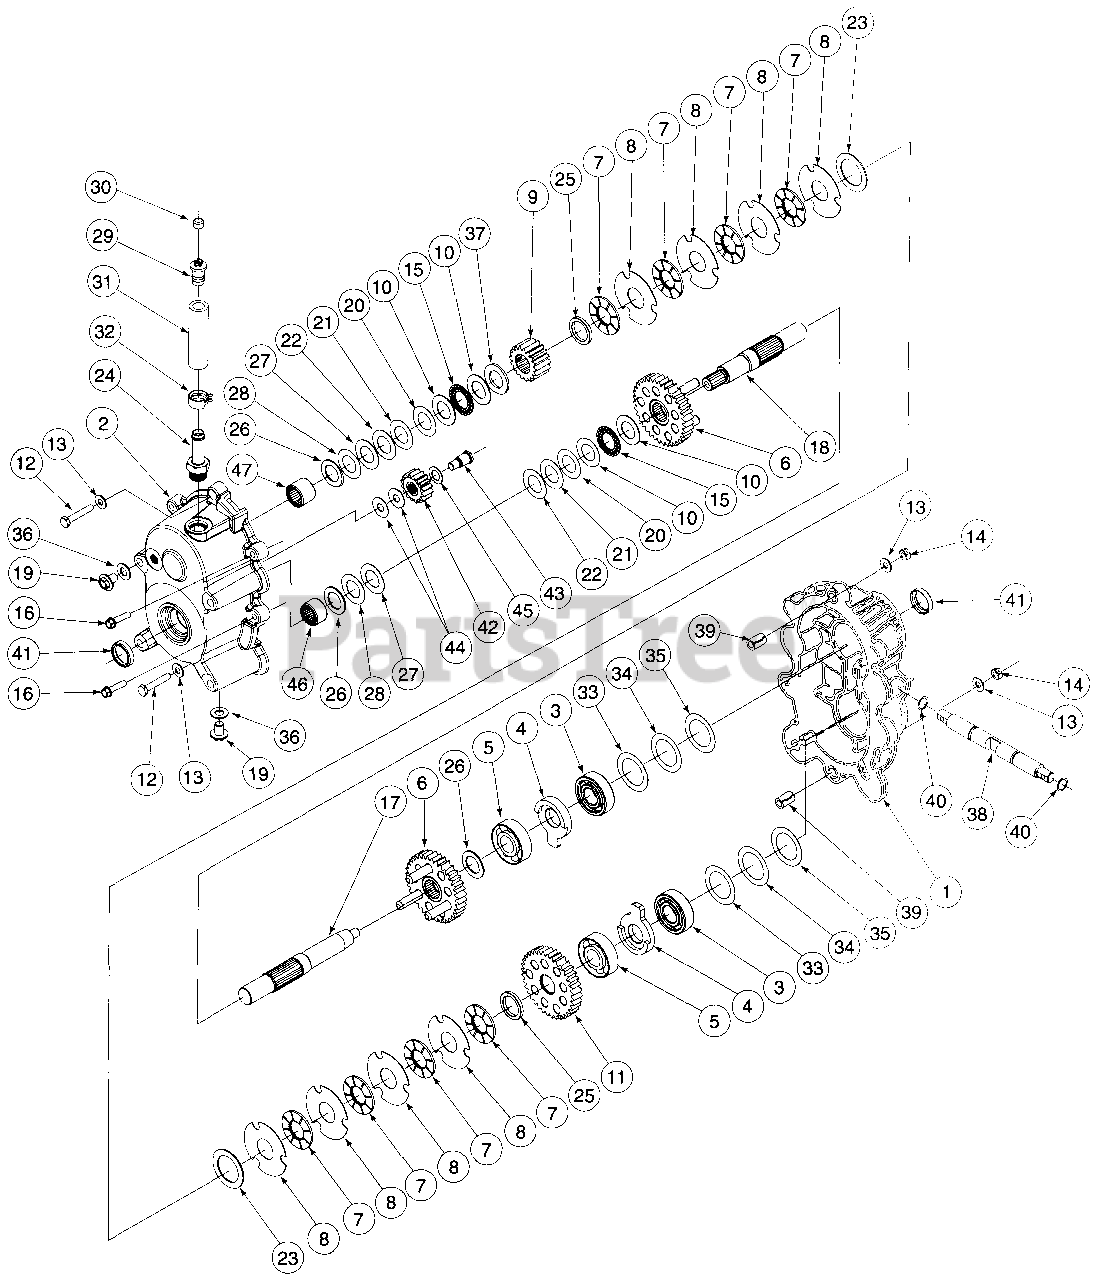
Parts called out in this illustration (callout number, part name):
1	Housing, Front Clutch
2	Housing, Rear Clutch
3	Bearing, Ball, .787 x 1.85 x .551
4	Fulcrum, Clutch
5	Bearing, Angular Contact
6	Carrier Assembly, Clutch
7	Plate, Clutch
8	Disc, Friction
9	Gear, 18T Drive
10	Washer, Thrust, .793 x 1.369 x .039
11	Gear, 36T
12	Screw, Hex Cap, 1/4-20 x 1.5
13	Washer, Flat, .25 ID x .62 OD
14	Nut, Hex Top Lock, 1/4-20
15	Bearing, Needle, .825 x 1.368 x .078
16	Screw, Hex Wash Hd Tapp 1/4-20 x 1.0
17	Shaft, Clutch Input
18	Shaft, Clutch Output
19	Screw, Hex Plug, 3/8-16 x .438
20	Washer, Flat, .793 x 1.368 x .015
21	Washer, Flat, .793 x 1.368 x .020
22	Washer, Flat, .793 x 1.368 x .025
23	Washer, Flat, 1.25 x 1.80 x .062
24	Tube Fitting, 1/2 Hose, 3/4-16 Thrd
25	Spacer, Clutch, .915 x 1.25 x .148
26	Washer, Flat, .793 x 1.24 x .060 Hdn
27	Washer, Flat, .793 x 1.368 x .005
28	Washer, Flat, .793 x 1.368 x .010
29	Vent, Plastic, .50 ID Hose
30	Cap, Plastic Vent
31	Line, Fuel, 1/2" ID 7.75 Long
32	Clamp, Hose
33	Washer, Flat, 1.25 x 1.80 x .015
34	Washer, Flat, 1.25 x 1.80 x .005
35	Washer, Flat, 1.25 x 1.80 x .010
36	Washer, Flat, .390 x .687 x .062
37	Washer, Flat, .812 x 1.38 x .10
38	Shaft, Clutch Actuator
39	Bushing, Dowel
40	O-Ring, 1/2 ID x 5/8 OD
41	Seal, Oil
42	Gear Assembly, 16T Reverse Idler
43	Shaft, Reverse Idler Gear
44	Washer, Flat, .385 x 1.0 x .030
45	Washer, Flat, .510 x .86 x .030
46	Bearing, Needle, .787 x 1.024 x .625
47	Bearing, Needle, .787 x 1.024 x .787
